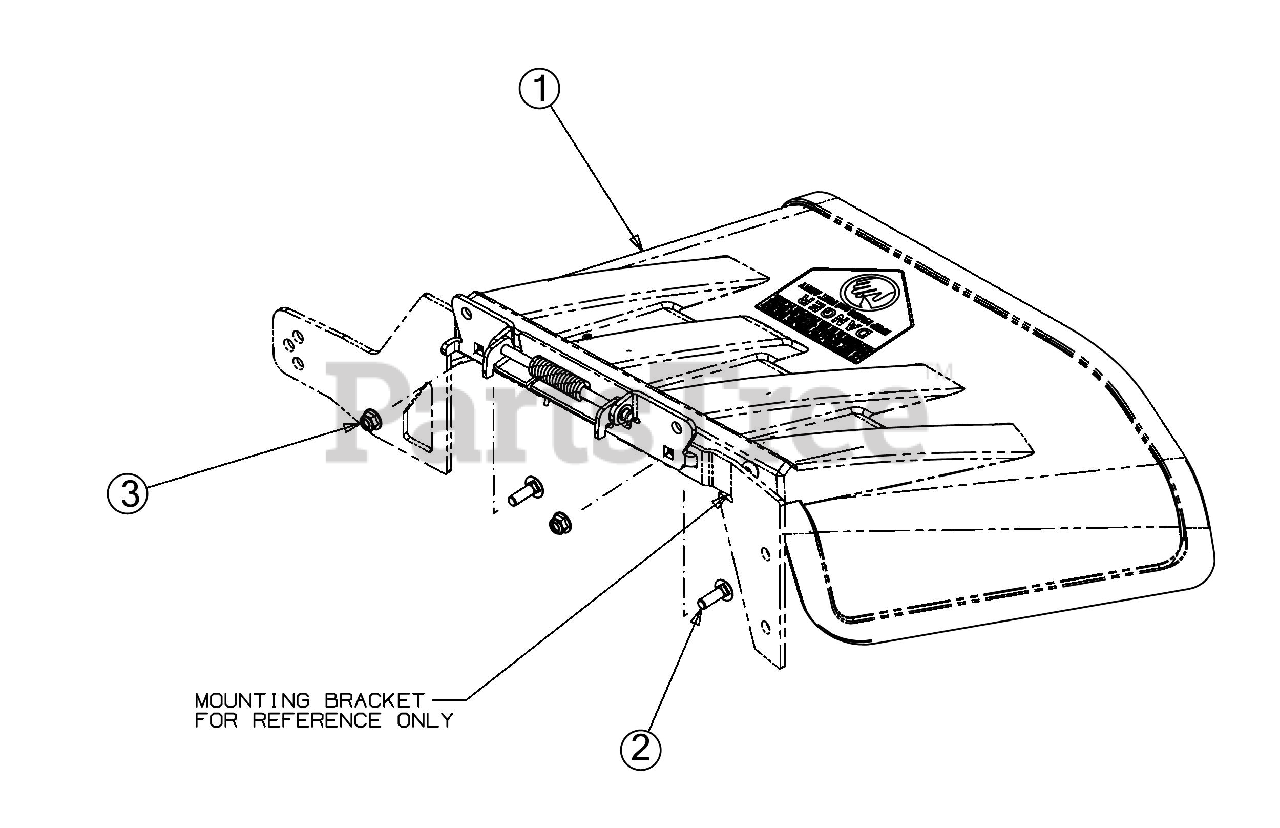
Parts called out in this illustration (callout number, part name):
1	CHUTE ASSEMBLY
2	CARRIAGE BOLT 5/16-18 X 1.00
3	FLANGE LOCK NUT 5/16-18
